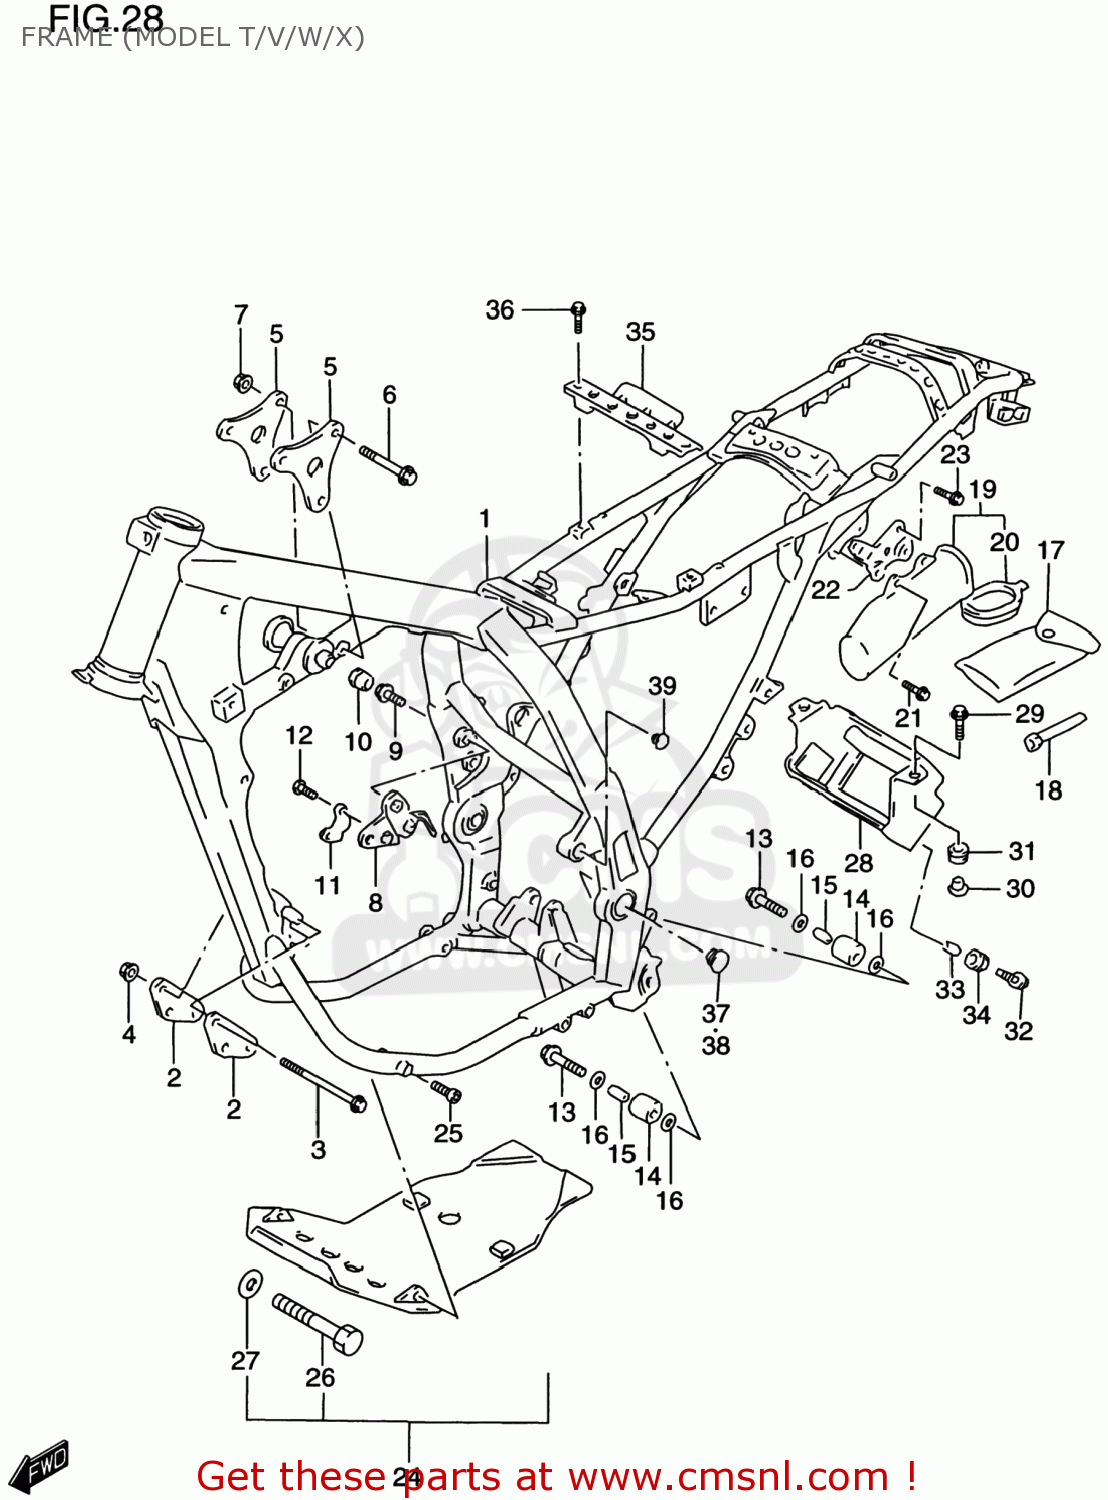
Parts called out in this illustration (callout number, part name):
1	FRAME COMP
2	PLATE,ENG MTG FR
3	BOLT(8X100)
4	NUT
5	PLATE,ENG MTG UPR
6	BOLT
7	NUT
8	PLATE,ENG MTG RR,R
9	BOLT
10	PLUG(OD:22)
11	BRACKET,STOP SWITCH
12	SCREW
13	BOLT(8X38)
14	ROLLER,CHAIN CONTROL UPR
15	SPACER(8.6X12X25.5)
16	WASHER
17	TOOL ASSY
18	SPARK PLUG WRENCH(16)
19	HOLDER,TOOL
20	CAP,HOLDER
21	BOLT(6X16)
22	BRACKET,TOOL HOLDER
23	BOLT
24	Skid Plate
25	BOLT(8X14)
26	BOLT(10X245)
27	WASHER(10X24X2)
28	HOLDER,BATTERY
29	BOLT(6X20)
30	WASHER
31	CUSHION
32	BOLT(6X16)
33	SPACER(6.1X9X7.5)
34	CUSHION
35	PLATE,BATTERY FITING
36	BOLT
37	PLUG,FRAME PIVOR,R
38	PLUG,FRAME PIVOR,L
39	PLUG,FRAME BOSS
